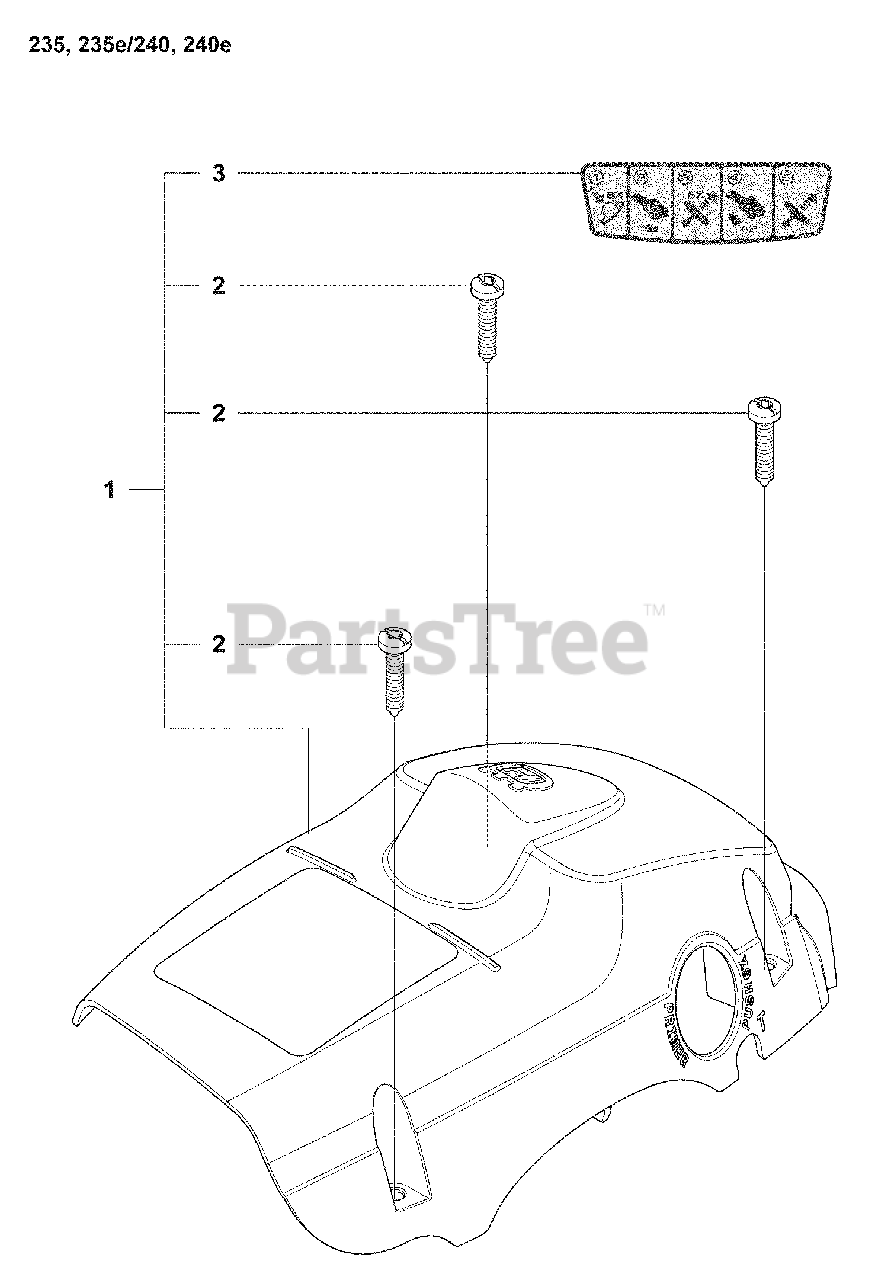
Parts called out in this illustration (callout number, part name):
1	CYLINDER SHIELD
2	SCREW, CYL SHIELD
3	Starting reminder decal
